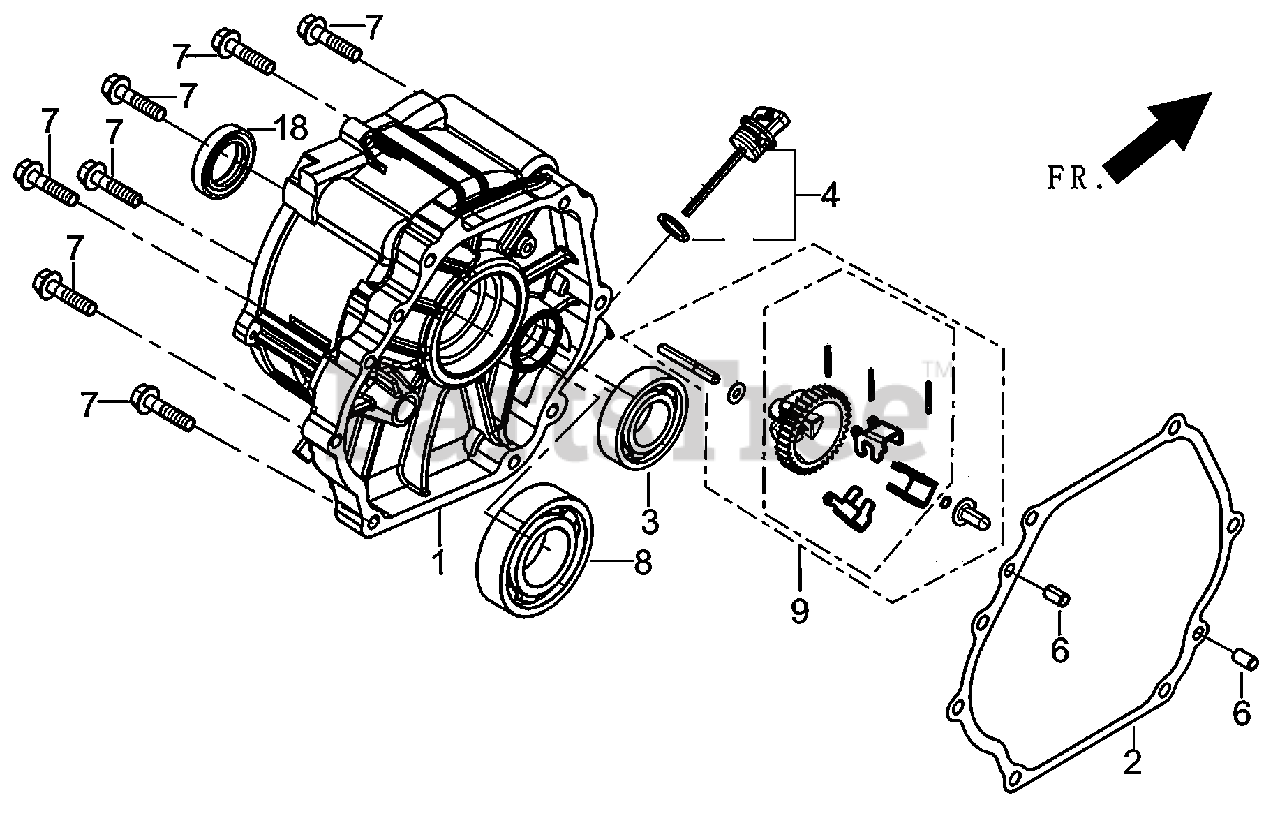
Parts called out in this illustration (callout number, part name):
1	COVER, CRANKCASE
2	GASKET, CRANKCASE
4	DIPSTICK SUBASSEMBLY, OIL
6	PIN, DOWEL
9	GEAR ASSY, GOVERNOR
18	SEAL, OIL
